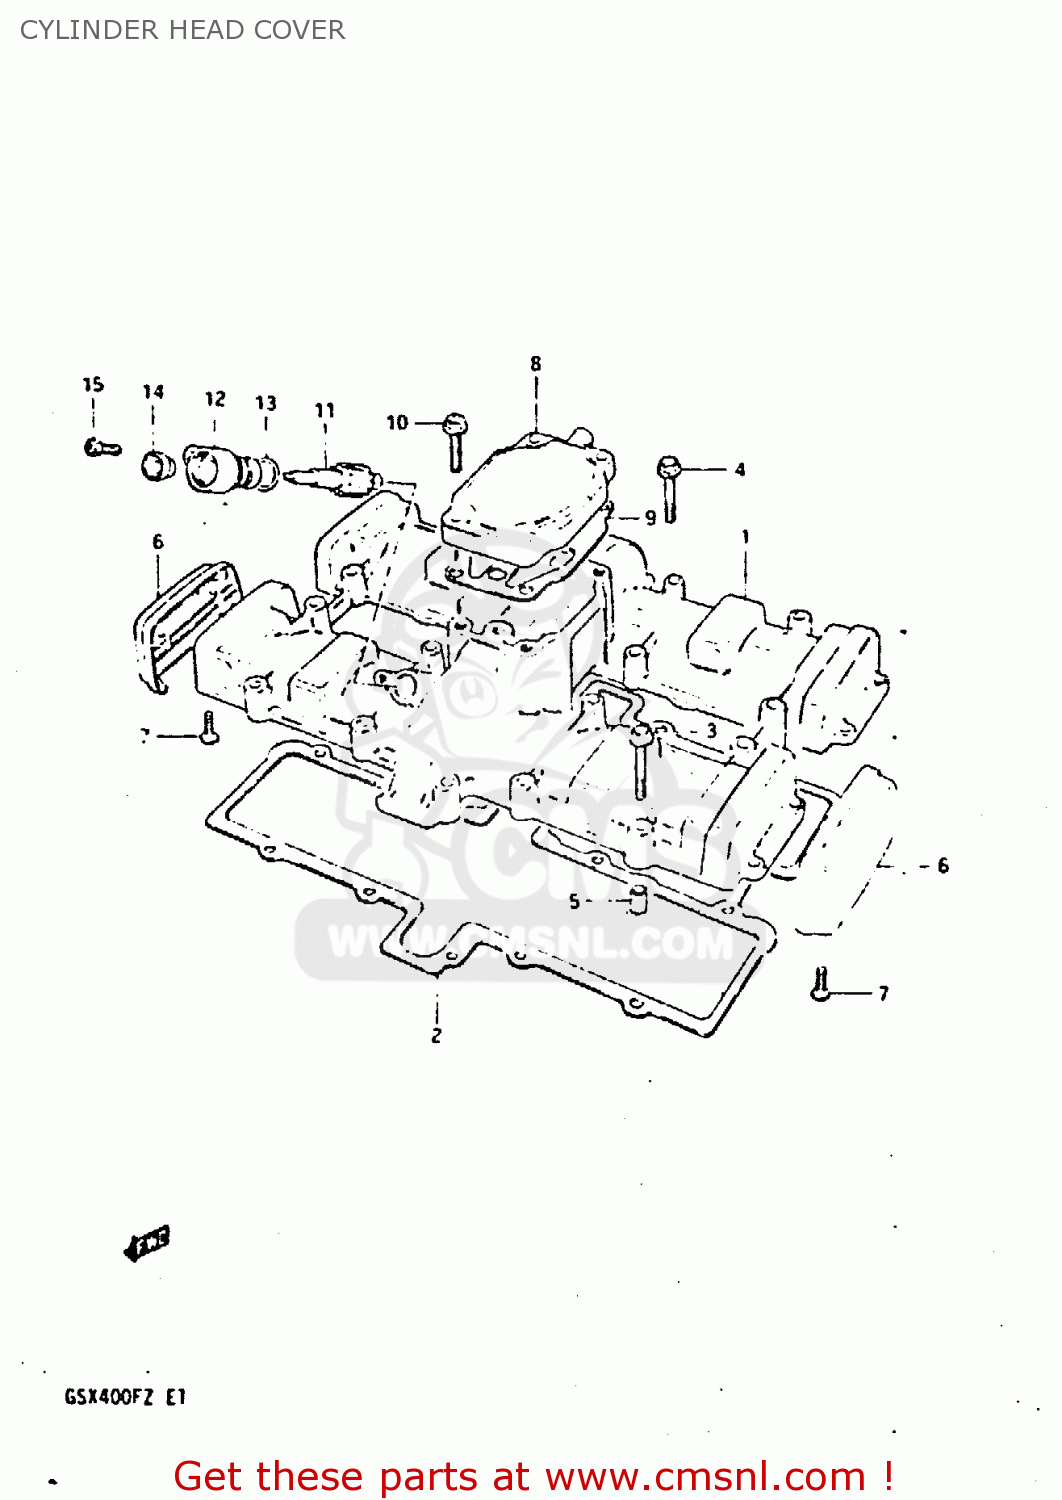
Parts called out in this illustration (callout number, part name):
1	COVER, CYLINDER HEAD
2	GASKET (MCA)
3	BOLT
4	BOLT 6X35
5	PIN(6.2X8X11)
6	CAP,CYLINDER H
7	SCREW
8	COVER,BREATHER
9	GASKET (MCA)
10	BOLT
11	GEAR,TACHOMETER DRIVEN
12	SLEEVE,TACHOMETER DRIVE GEAR
13	SEAL,TACHOMETER DRIVEN
14	SEAL,OIL(5X12X8)
15	SCREW(5X12)
